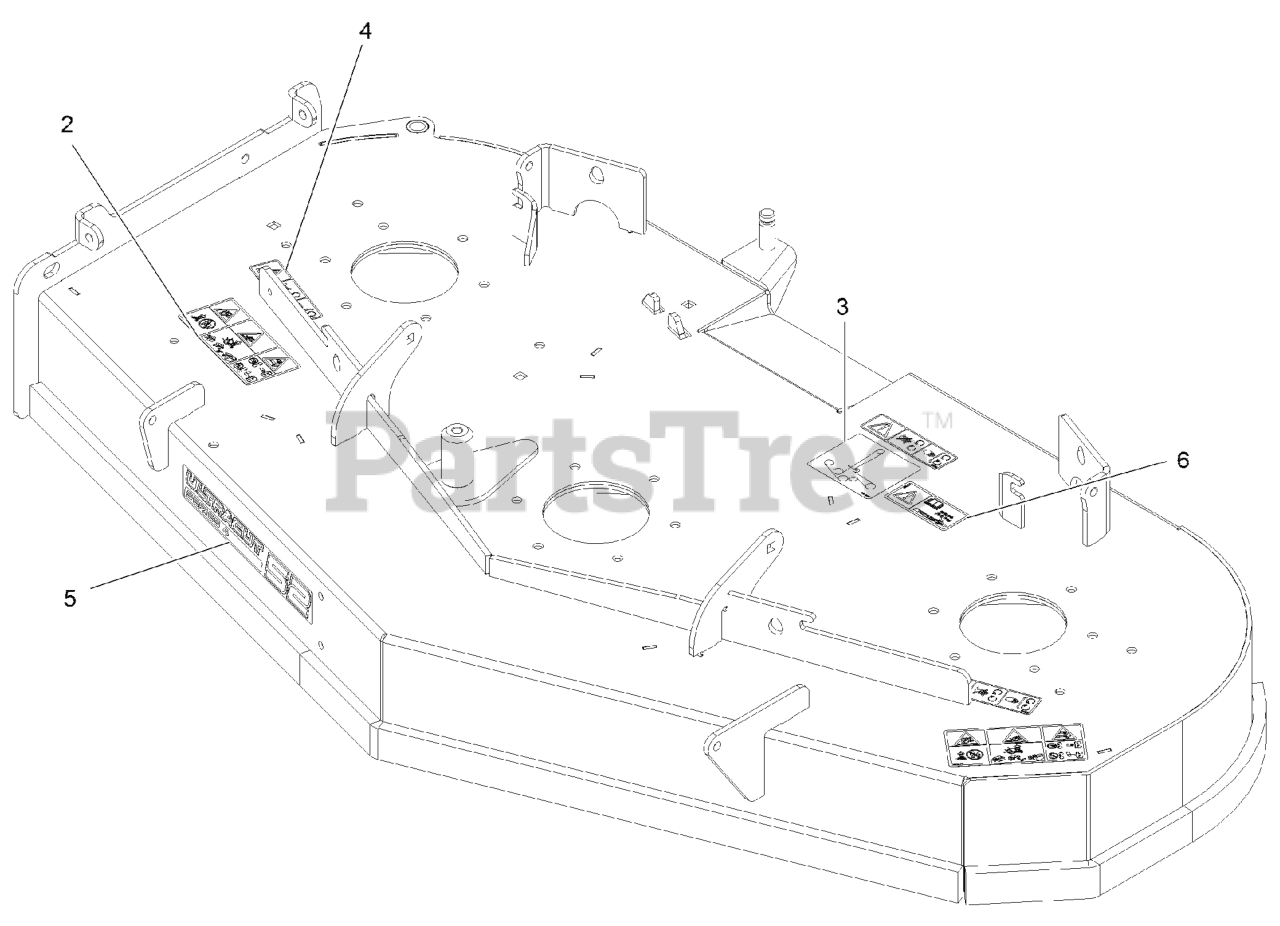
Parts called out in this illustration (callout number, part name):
2	DECAL-WARNING THROWN OBJ
3	DECAL-BELT ROUTING
4	DECAL-COVER, MISSING
5	DECAL, 524
6	DECAL-TORQUE, BOLT
